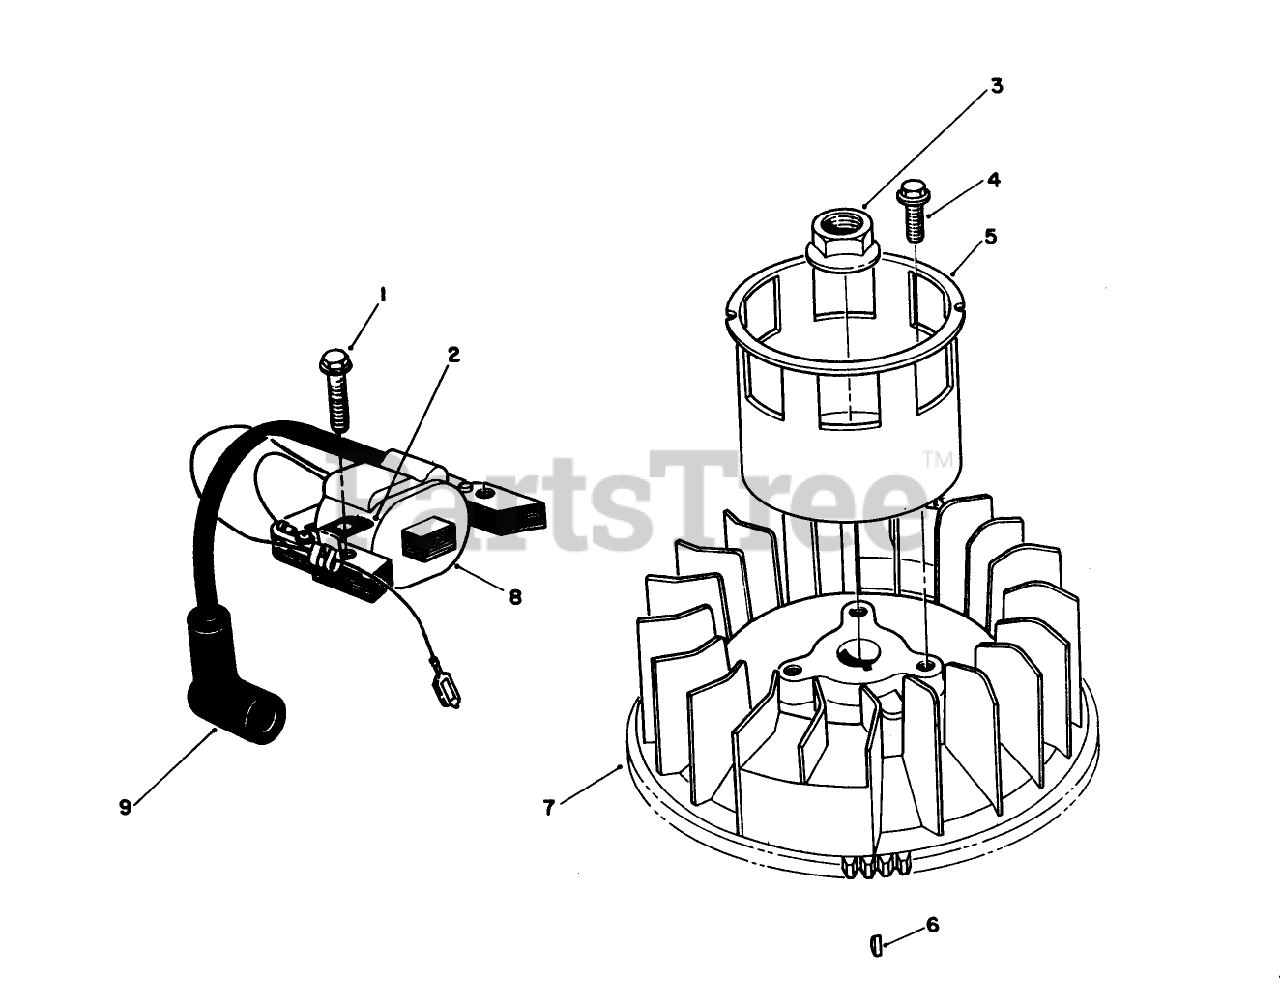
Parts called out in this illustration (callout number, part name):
2	CLAMP
7	FLYWHEEL
8	COIL ASM
9	Cover-Spar Plug
